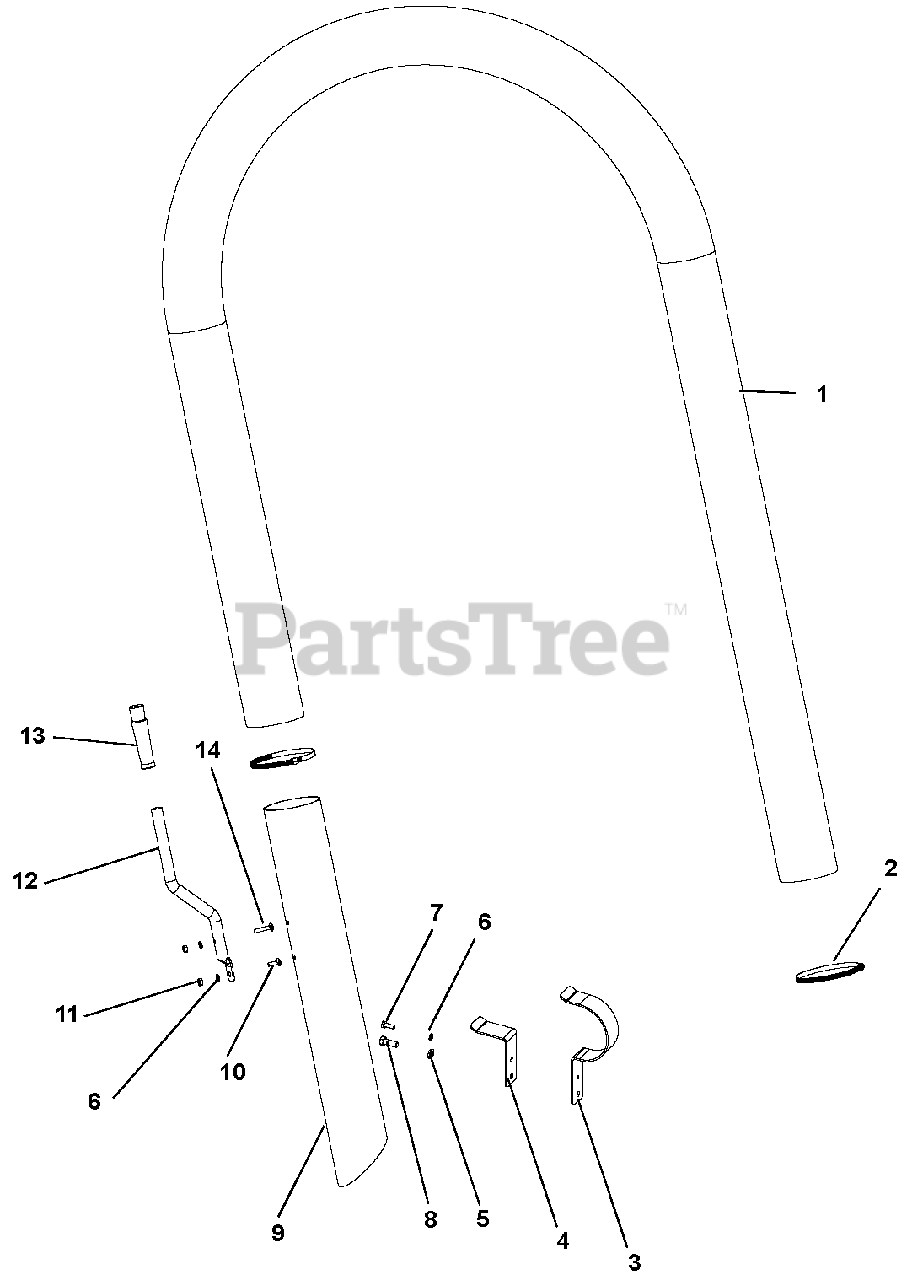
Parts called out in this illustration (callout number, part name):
1	Hose 4" X 10' Tigerflex LKC400
2	Clamp, Hose 4.50 Diameter .50 Band
3	Hose Guide, Inner
4	Hose Guide, Outer
5	Washer, Locking .38 X .094 Regular
6	Washer, Locking .25 X .062 Regular
7	Bolt, Hex .25-20 X .75
8	Bolt, Hex .38-16 X 1.00
9	Hose Extension Machined
10	Bolt, Round Head Square Neck .25-20 X .75
11	Nut, Hex .25-20
12	APV Handle for Hose Assembly
13	Grip, Handle, Black (23-3160-09-01)
14	Bolt, Round Head Square Neck .25-20 X 1.25
